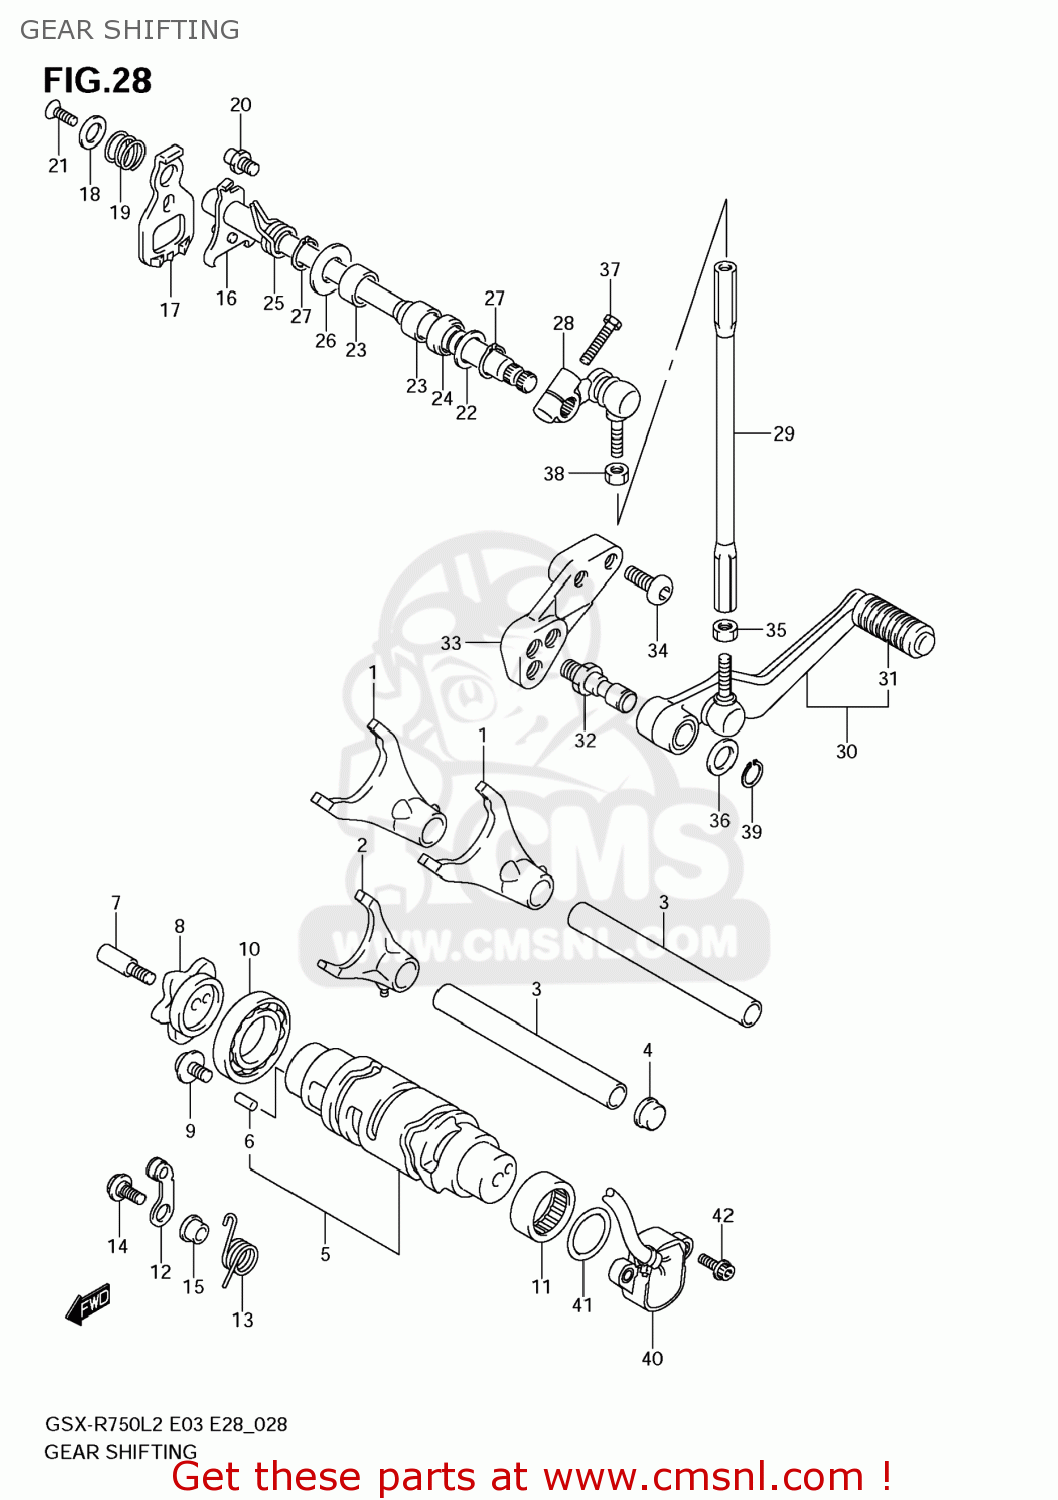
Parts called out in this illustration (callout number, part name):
1	FORK,GEAR SHIFT NO.1
2	FORK,GEAR SHIFT NO.3
3	SHAFT,GEAR SHIFT FORK NO.1
4	PLUG,GEAR SHIFT FORK SHAFT
5	CAM,GEAR SHIFT
6	PIN
7	BOLT,GEAR SHIFT CAM PLATE
8	PLATE,GEAR SHIFT CAM
9	SCREW(6X12)
10	BEARING(25X47X8)
11	BEARING(25X32X12)
12	STOPPER,SHIFT CAM
13	SPRING,GEAR SHIFT CAM STOPPER
14	BOLT,SHIFT CAM STOPPER ARM
15	SPACER,CAM STOPPER
16	SHAFT,GEAR SHIFT
17	PLATE,GEAR SHIFT CAM DRIVE
18	WASHER,GEAR SHIFT SHAFT END
19	SPRING,GEAR SHIFT PLATE RETURN
20	STOPPER,GEAR SHIFT ARM
21	SCREW(6X16)
22	WASHER(14X29X0.8)
23	BEARING(14X20X12)
24	SEAL,OIL(14X22X7.3)
25	SPRING
26	SHIM(14X24X1)
27	CIRCLIP
28	ARM,GEAR SHIFT LINK
29	ROD,GEAR SHIFT LINK
30	LEVER ASSY,GEAR SHIFT
31	RUBBER,GEAR SHIFT PEDAL
32	SHAFT,GEAR SHIFT LEVER
33	BRACKET,GEAR SHIFT LEVER
34	BOLT(8X20)
35	NUT
36	WASHER(12.5X20X1)
37	BOLT
38	NUT
39	CIRCLIP
40	SENSOR ASSY,GEAR POSITION
41	O RING(D:2.4,ID:26.2)
42	BOLT(5X16)
